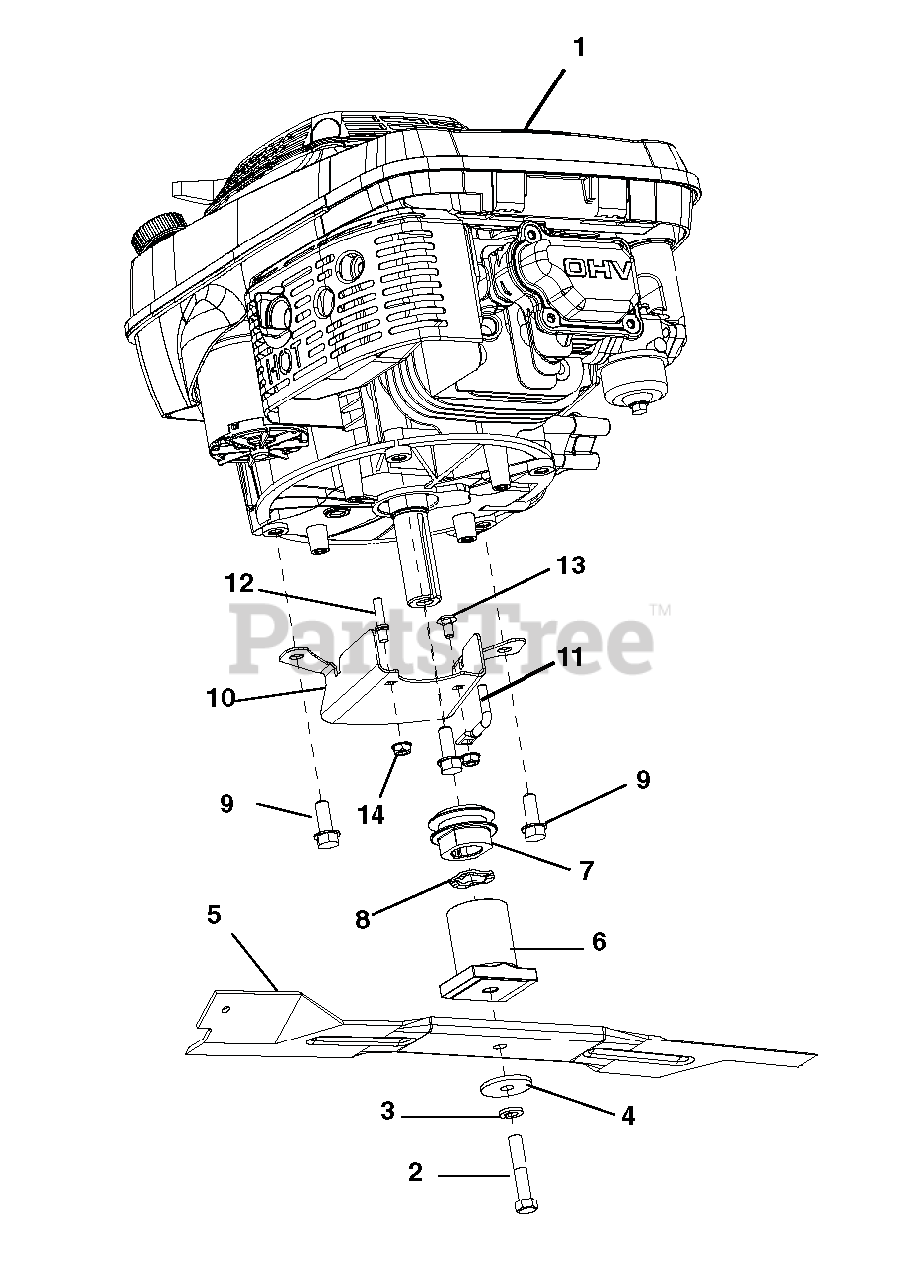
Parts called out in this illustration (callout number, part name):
1	ENGINE, KAWI FJ180V COMMERCIAL
2	BLT-HEX .38-24 X 2.00 GR8 YWZC
3	@WSHR-LK .38X.094 REG YWZC
4	WSHR-FL-STL .390X1.5X.125 YWZC
5	BLADE, 21" LM MULCHING
6	ADAPTER, CE BLADE
7	PULLEY-SINTERED IRON LM
8	WASHER-WAVE .885X1.311X.125
9	@SCR-TAP .38-16X1.00 HWH TR YZ
10	CHANNEL, XD21 FRONT BELT
11	FINGER, BELT
12	FINGER, BELT
13	@BLT-RDHDSQNK .25-20X.50 G5YZ
14	@NUT-SPNLK-FLG .25-20 YWZC
